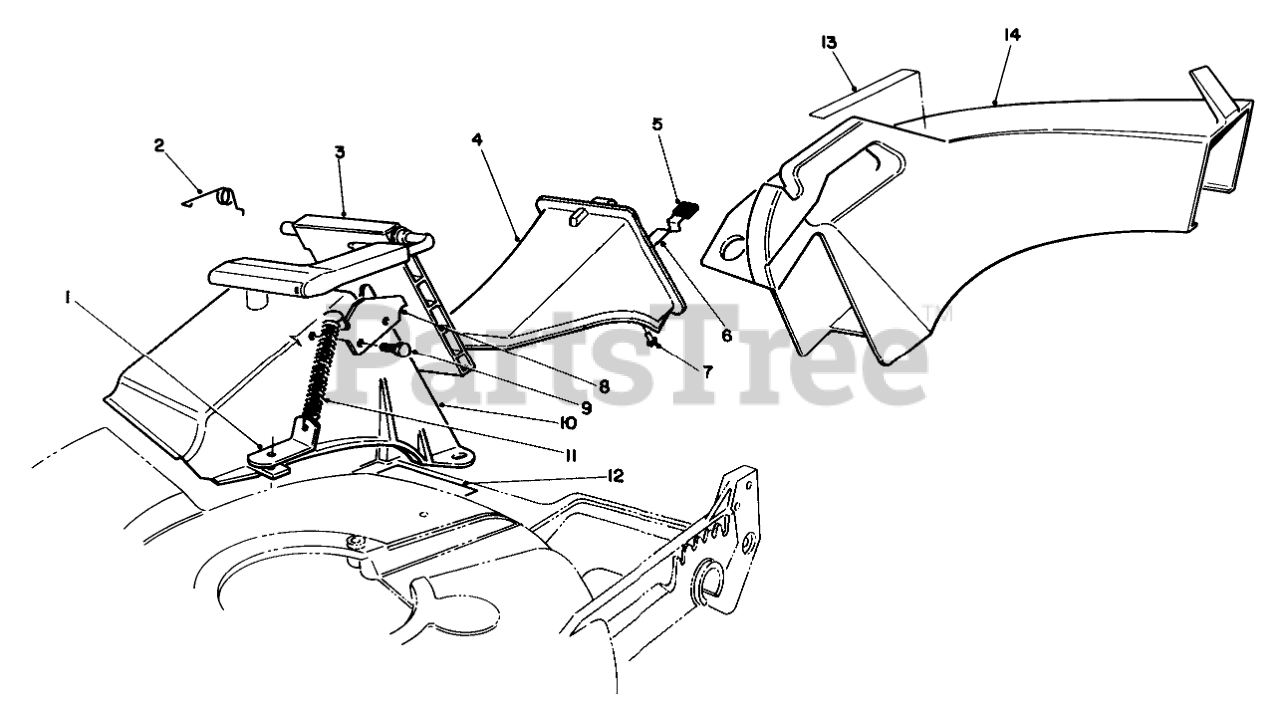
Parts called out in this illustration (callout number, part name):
1	Bracket-Spring
2	RETAINER-DOOR
3	DOOR ASSEMBLY
4	Plug Assembly (Incl. Ref. #5-7)
5	GRIP-LATCH
6	LATCH-PLUG, DISCHARGE
7	RIVET-HEAD, FLAT
8	DOOR LATCH PLATE
9	SCREW-PLASTITE
10	DISCHARGE TUNNEL
11	SPRING-DOOR
12	DECAL - CAUTION
13	DECAL - WARNING
14	Chute-Discharge (Incl. Ref. #13)
